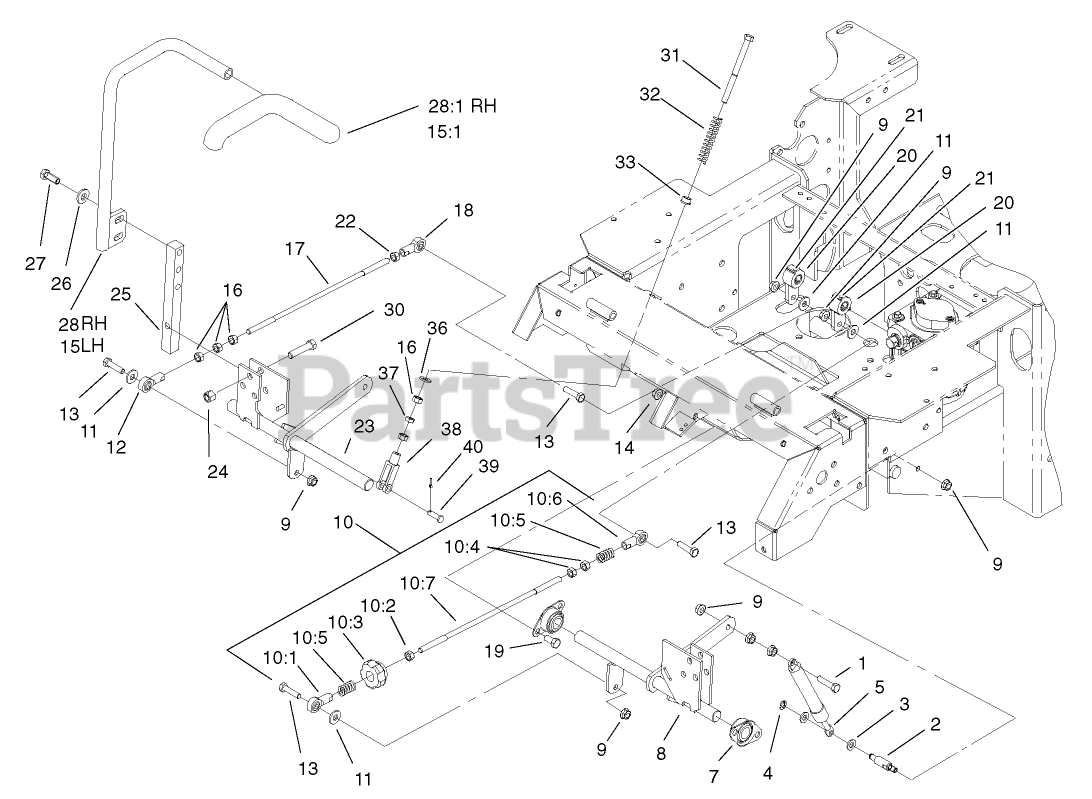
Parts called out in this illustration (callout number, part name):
1	SCREW-HH
2	PIN-DAMPER
3	WASHER-PLAIN
4	RING-RETAINING, EXT
5	Damper-Control, Motion
7	BEARING-FLANGE, SIDE
8	LH Motion Control ASM
9	NUT-HF
10	Tracking Rod ASM
10:1	BALLJOINT-RH
10:2	NUT-HEX
10:3	KNOB-TRACKING
10:5	SPRING-COMPRESSION
10:6	BALLJOINT-LH
10:7	Link-Rod, Tracking
11	WASHER-FLAT
12	BALLJOINT-RH
13	SCREW-HH
14	NUT-HHF, WHIZ
15	LH LEVER ASM
15:1	GRIP-CONTROL, MOTION
16	NUT-HEX
17	LINKAGE-PUMP/LEVER
18	BALLJOINT-LH
19	SCREW-HH
20	ARM-CONTROL, PUMP
21	SCREW-SET
23	RH Motion Control ASM
24	NUT-LOCK, NI
25	ARM-SHAFT, CONTROL
26	WASHER-BELLEVILLE
27	SCREW-HH
28	RH LEVER ASM
28:1	GRIP-CONTROL, MOTION
30	SCREW-HH
31	BOLT-RETURN, NEUTRAL
32	SPRING-RETURN, NEUTRAL
33	BUSHING-FLANGED
36	WASHER-FLAT
37	NUT-JAM
38	YOKE-ADJUSTABLE
39	PIN-CLEVIS
40	PIN-COTTER
